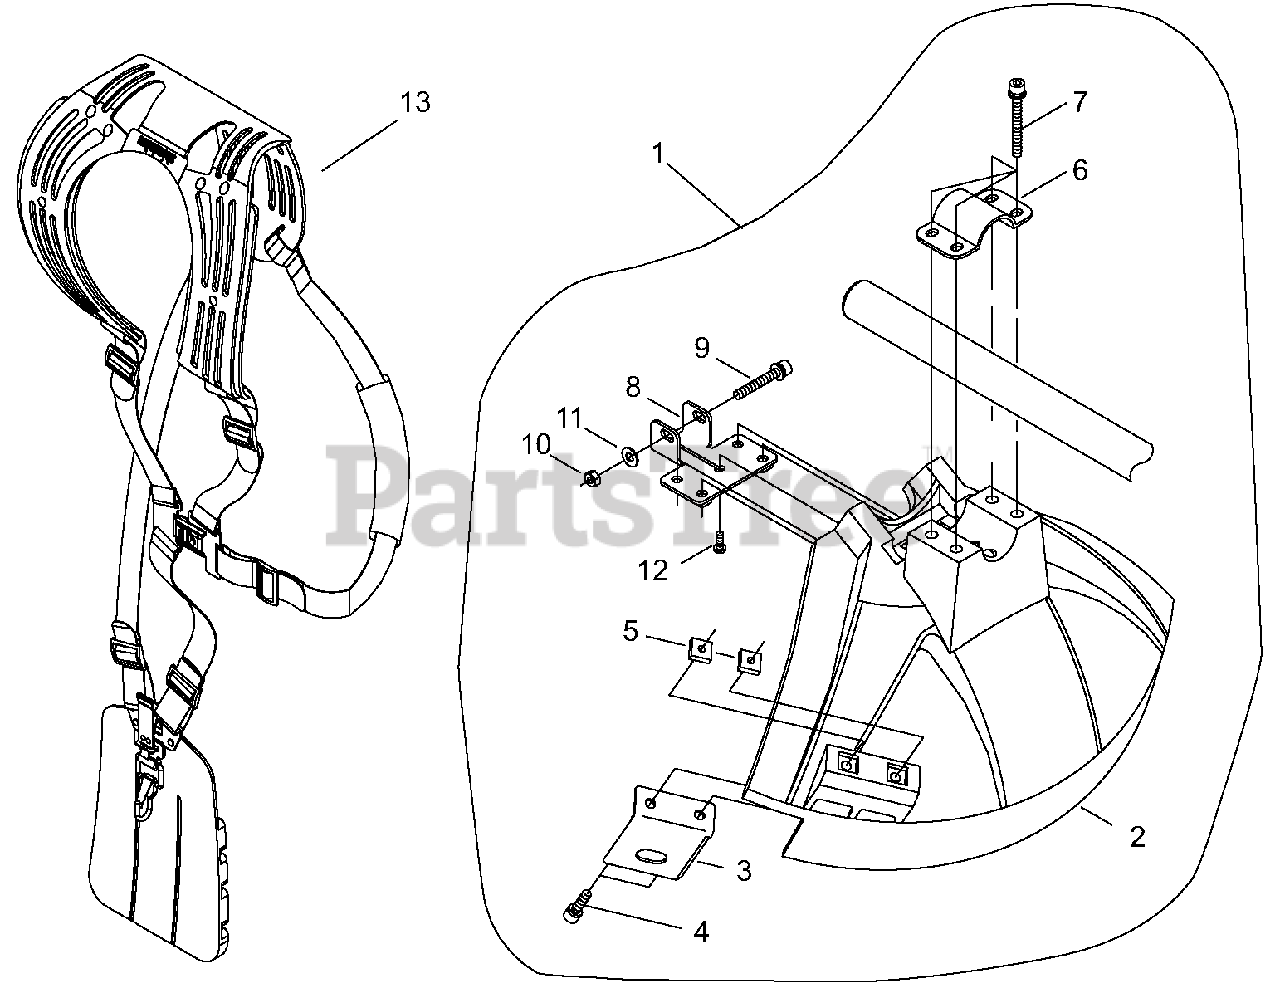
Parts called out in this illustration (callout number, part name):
1	DEBRIS SHIELD ASSY
2	SHIELD, DEBRIS - BLACK
3	KNIFE, TRIMMER LINE
4	SCREW - 5X16
5	NUT - 5
6	CLAMP - UPPER
7	SCREW - 5X45
8	CLAMP - LOWER
9	SCREW - 6X40
10	LOCKNUT - 6
11	WASHER - 6
12	SCREW
13	HARNESS ASSY
